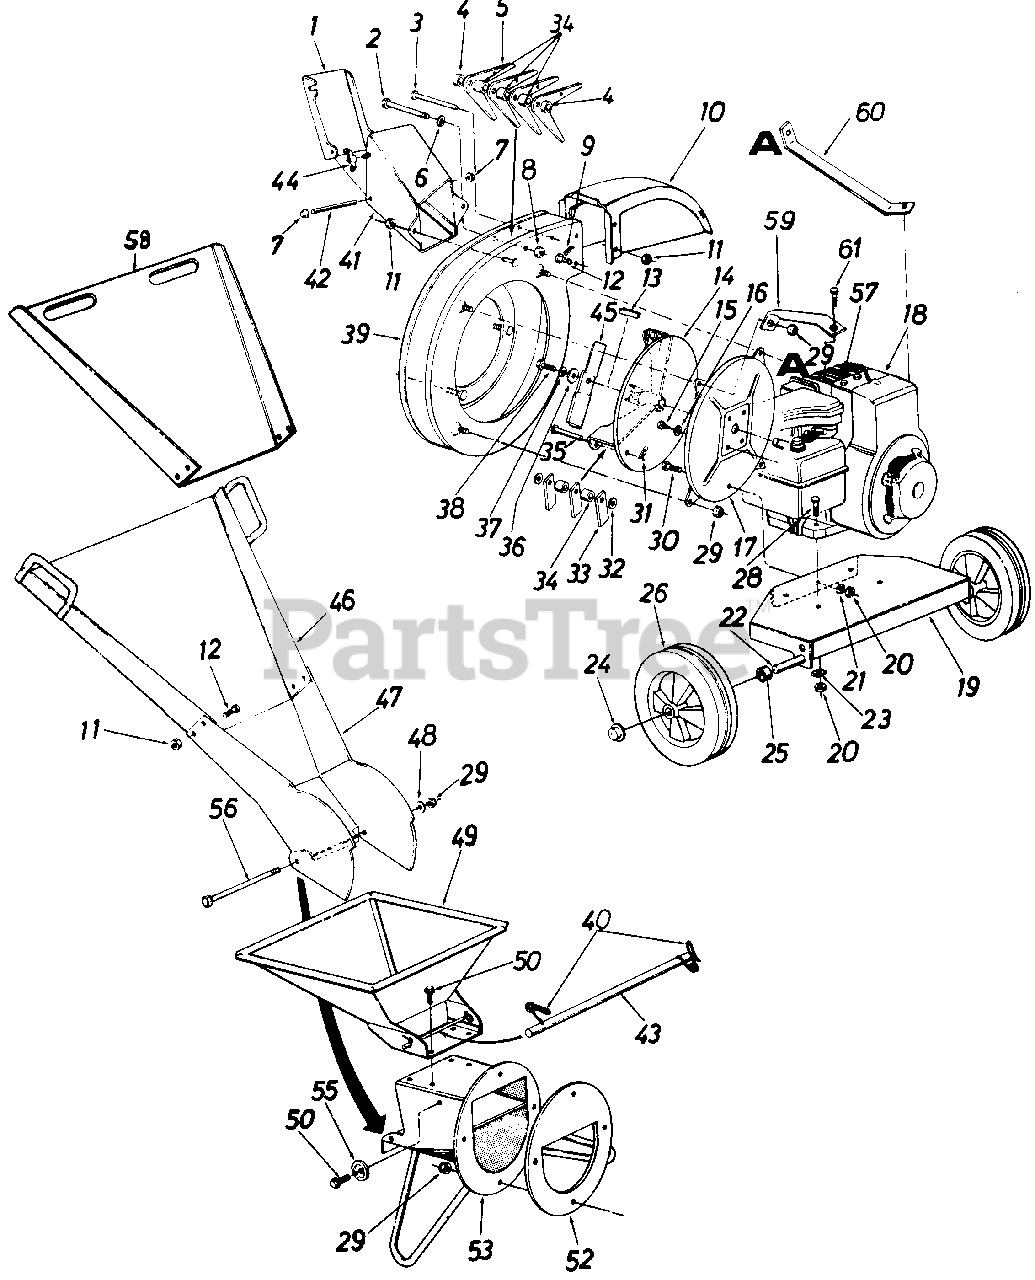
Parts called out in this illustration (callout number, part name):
1	Door Chip It
2	Hex Bolt 1/2-20 x 4.50" Lg.*
3	Clevis Pin
4	Flail Spacer 7/32" Lg.
5	Cutting Finger
6	L.-Wash. 1/2" I.D.*
7	Palnut 3/16" Dia.
8	Hex Jam Nut 1/2-20 Thd.*
9	Cotter Pin 3/32" Dia. x 3/4" Lg.
10	Chute Delfector
11	L.-Nut 1/4-20 Thd.
12	Hex Bolt 1/4-20 x .50" Lg.*
13	Sq. Key 1/4" x 2.00" Lg.
14	Impeller Assembly
15	Hex Bolt 5/16-24 x 3/4" Lg.
16	L.-Wash. 5/16" I.D.*
17	Hopper to Engine Mtg. Plate
18	Engine
19	Engine Mounting Plate
20	Hex Nut 5/16-24 Thd.*
21	L.-Wash. 5/16" I.D.*
22	Shaft
23	Special L.-Wash. 5/16" I.D.
24	Push Cap
25	Spacer
26	Wheel Ass'y.-Comp. (White)
28	Hex Bolt 5/16-24 x 1.50" Lq.*
29	Elastic Lock Nut 5/16-18 Thd.
30	Hex Bolt 5/16-24 x .62" Lg.*
31	Cotter Pin 1/8" Dia. x 1.00" Lq.*
32	Fl.-Wash. .531" I.D. x .937 O.D. x .09
33	Flail
34	Spacer 23/32" Lg.
35	Clevis Pin .50" Dia. x 3.0" Lg.
36	Fl.-Wash. .406" I.D. x 1.25" O.D. Hdn.
37	L.-Wash. 3/8" I.D. H.D.
38	Hex Bolt 3/8-24 x 2.0" Lg. H.T.
41	Chip lt Guide Ass'y.
42	Hinge Pin
43	Release Bar
44	Wing Nut Elastic 1/4-20 Thd.
47	Lower Leaf Ramp Section
48	Fl.-Wash. 5/16" I.D.
49	Hopper Assembly
50	Hex Wash. Hd. Self-Tap Scr. 5/16-18 x .75" Lg.
52	Back-Up Plate
53	Inlet Guide Assembly
55	Stop Washer
56	Hex Bolt 5/16-28 x 8.38" 4.
57	Spark Plug Boot
60	Impeller Hsg. Support Brace L.H. N
61	Part of Engine
